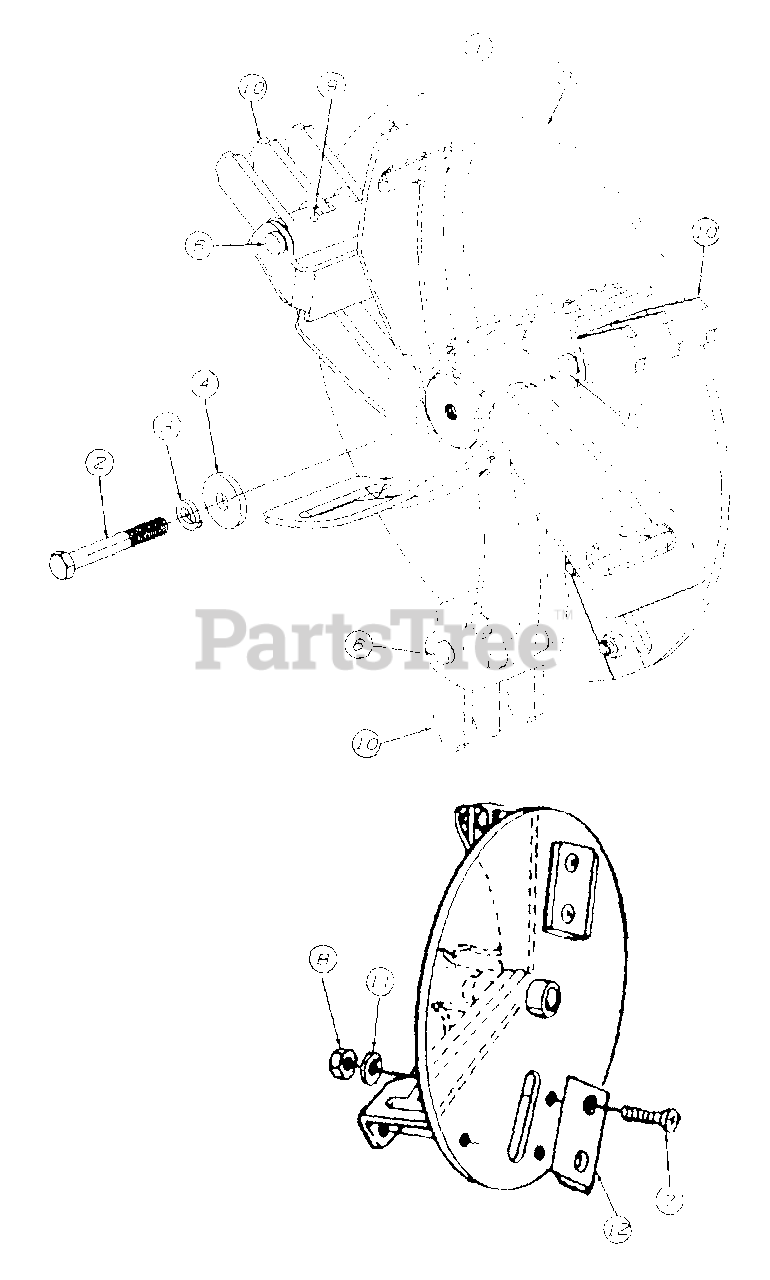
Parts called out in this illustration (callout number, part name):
1	IMPELLER ASSY COMP.
3	WASHER - LOCK
4	WASHER - FLAT
5	IMPELLER ASSY
6	PIN - CLEVIS
7	SCREW - FLAT HEAD
8	NUT - HEX LOCK
9	PIN - ROLL SPRING
10	BLADE - FLAIL
11	WASHER - LOCK
12	BLADE - CHIPPER
